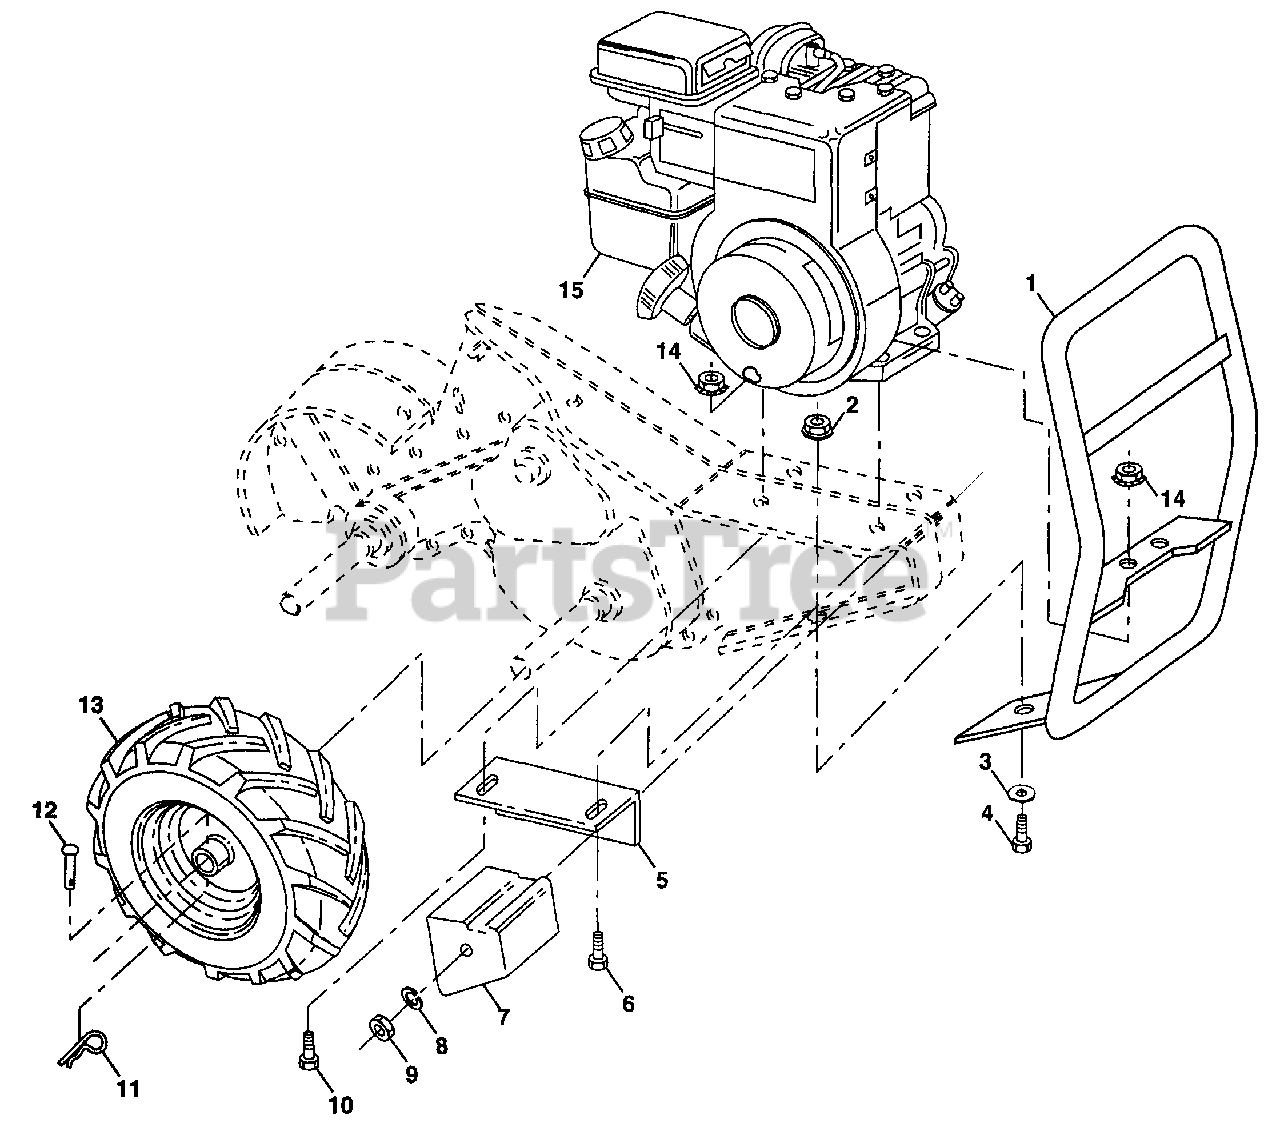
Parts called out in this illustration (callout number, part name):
1	Bumper
2	Locknut, Hex, Flange 5/16-18
3	Washer 11/32 x 11/16 x 16 Ga.
4	Bolt, Hex 5/16-18 x 3/4
5	Bracket, Reinforcement (AYP part number)
6	Bolt, Hex 5/16-18 x 2
7	Counter Weight, R.H. (AYP part number)
8	Washer, Lock 3/8
9	Nut, Hex 3/8-16
10	Bolt, Hex 5/16-18 x 1-1/2
11	Clip, Hairpin (AYP part number)
12	Rivet, Drilled
13	Tire
13	Rim (AYP part number)
13	Tire Valve (AYP part number)
14	Nut, Keps 5/16-18
15	Engine, Tec
